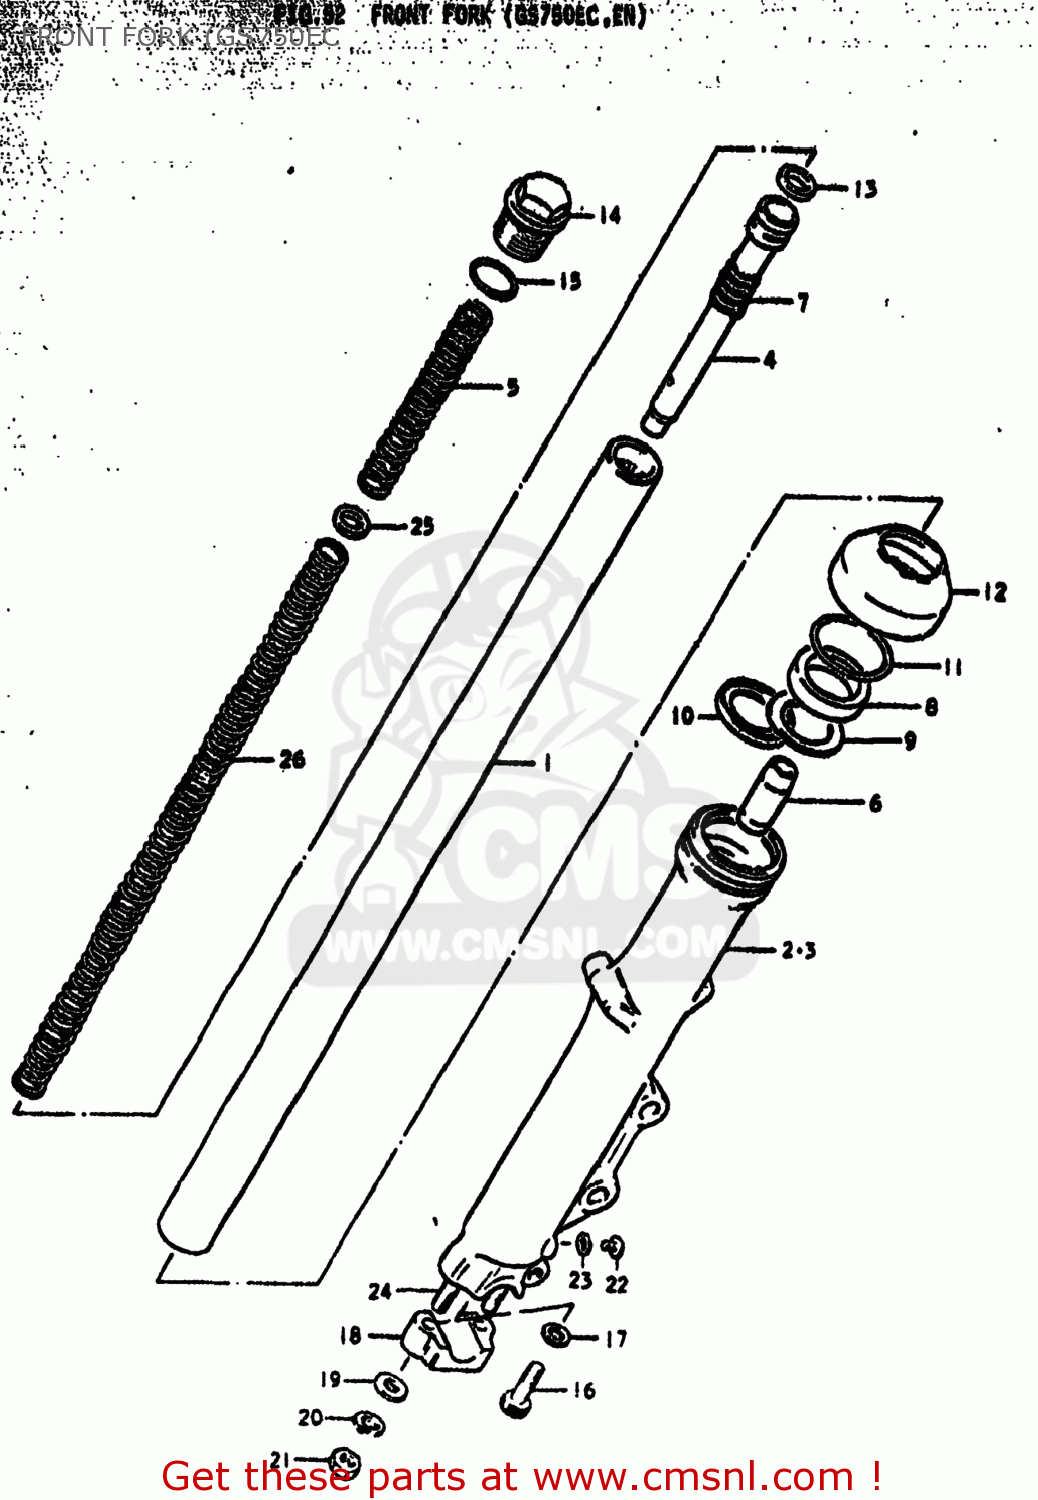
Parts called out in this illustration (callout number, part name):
0	DAMPER ASSEMBLY,LEFT
1	TUBE,INNER
2	TUBE,FORK,OUTER,RIGHT
3	TUBE,FORK,LEFT,OUTER
4	CYLINDER,FRONT FORK
5	SPRING,FRONT FORK,UPPER
6	PIECE,OIL LOCK
7	SPRING,FORK REBOUND
8	OIL SEAL,FRONT FORK
9	SPACER,SEAL
10	SPACER,SEAL
11	RING,OIL SEAL STOPPER
12	BOOT
13	RING
14	CAP,INNER TUBE
15	O RING
16	BOLT
17	GASKET (NAS)
18	HOLDER,AXLE
19	WASHER
20	LOCK WASHER
21	NUT
22	SCREW
23	GASKET (NAS)
24	STUD 8X25
25	WASHER
26	SPRING,FRONT FORK
